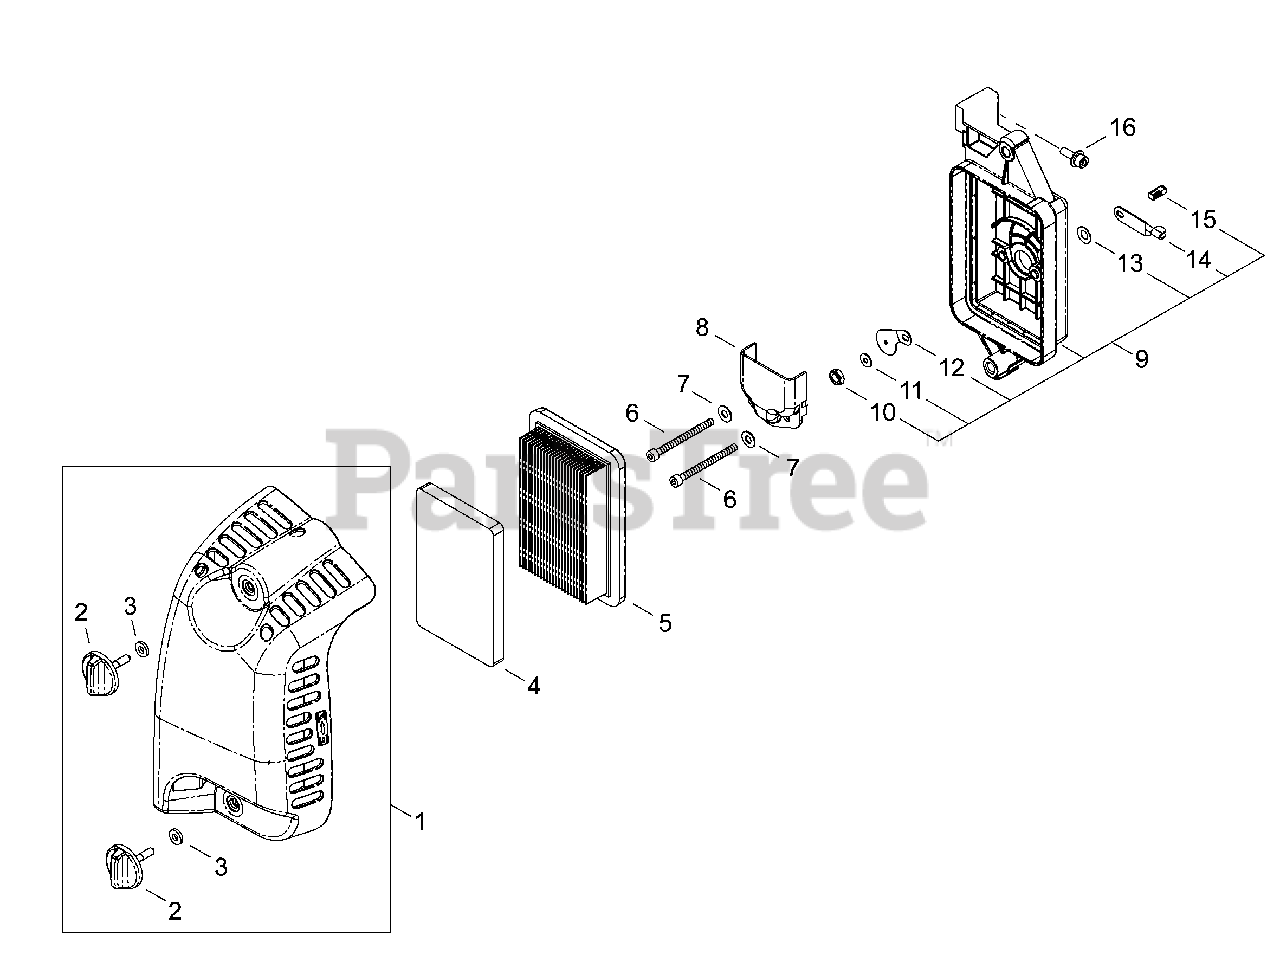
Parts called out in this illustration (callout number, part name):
1	AIR FILTER COVER ASSY
2	THUMBSCREW
3	WASHER - VINYL
4	PRE-FILTER - FOAM
5	FILTER, AIR
6	SCREW - 5X70
7	WASHER - 5
8	DEFLECTOR PLATE
9	CASE, AIR FILTER
10	NUT - 6
11	LOCKWASHER - 6
12	PLATE, CHOKE
13	WASHER - CONICAL
14	LEVER, CHOKE
15	SHAFT, CHOKE
16	SCREW - 5X20
